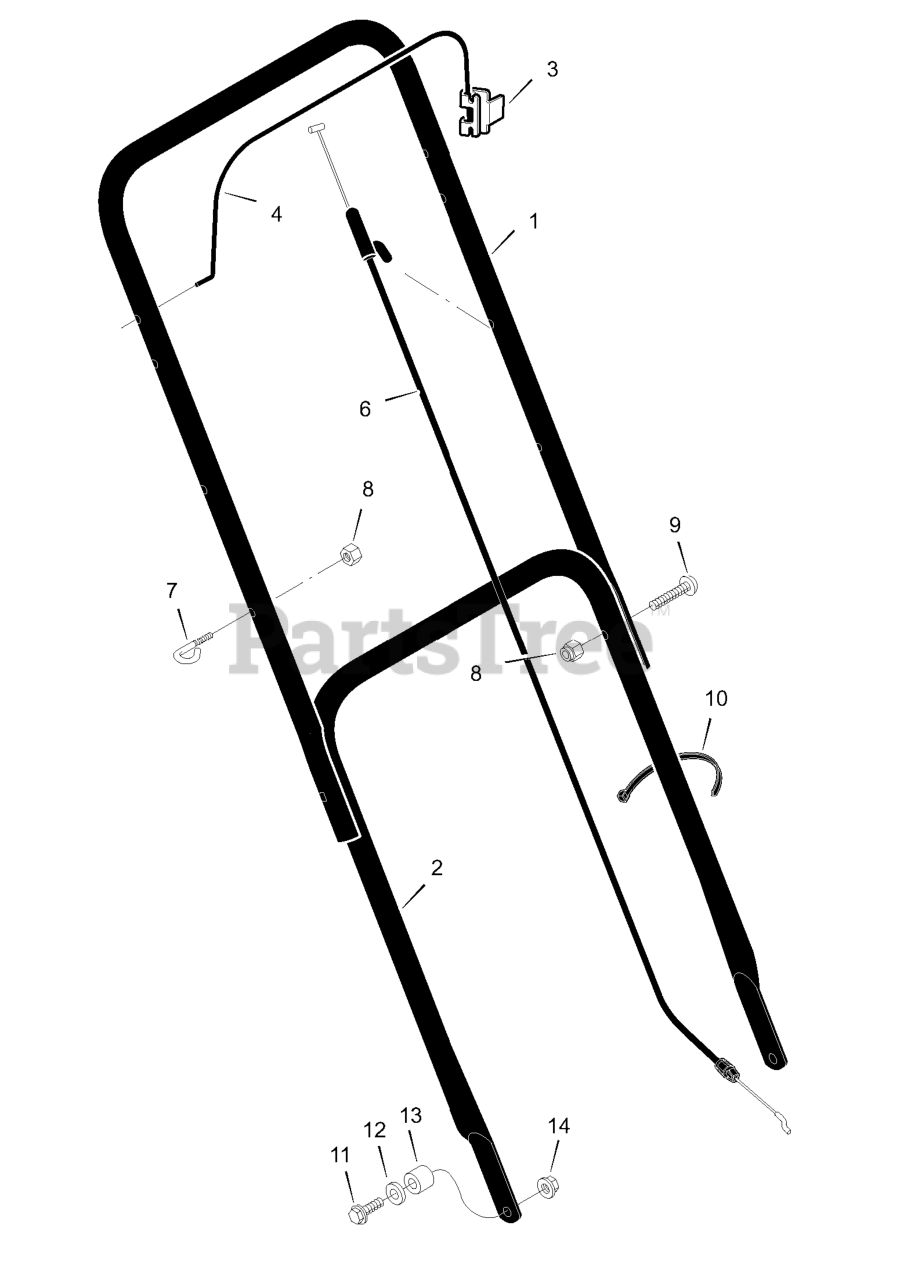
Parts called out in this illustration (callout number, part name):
1	Handle, Upper (Black)
2	Handle, Lower (Black)
3	Bracket, Stop Lever
4	Lever, Stop
6	Engine Stop Cable
7	GUIDE, ROPE
8	Locknut
10	Fastener, Cable
11	Bolt
14	Nut
